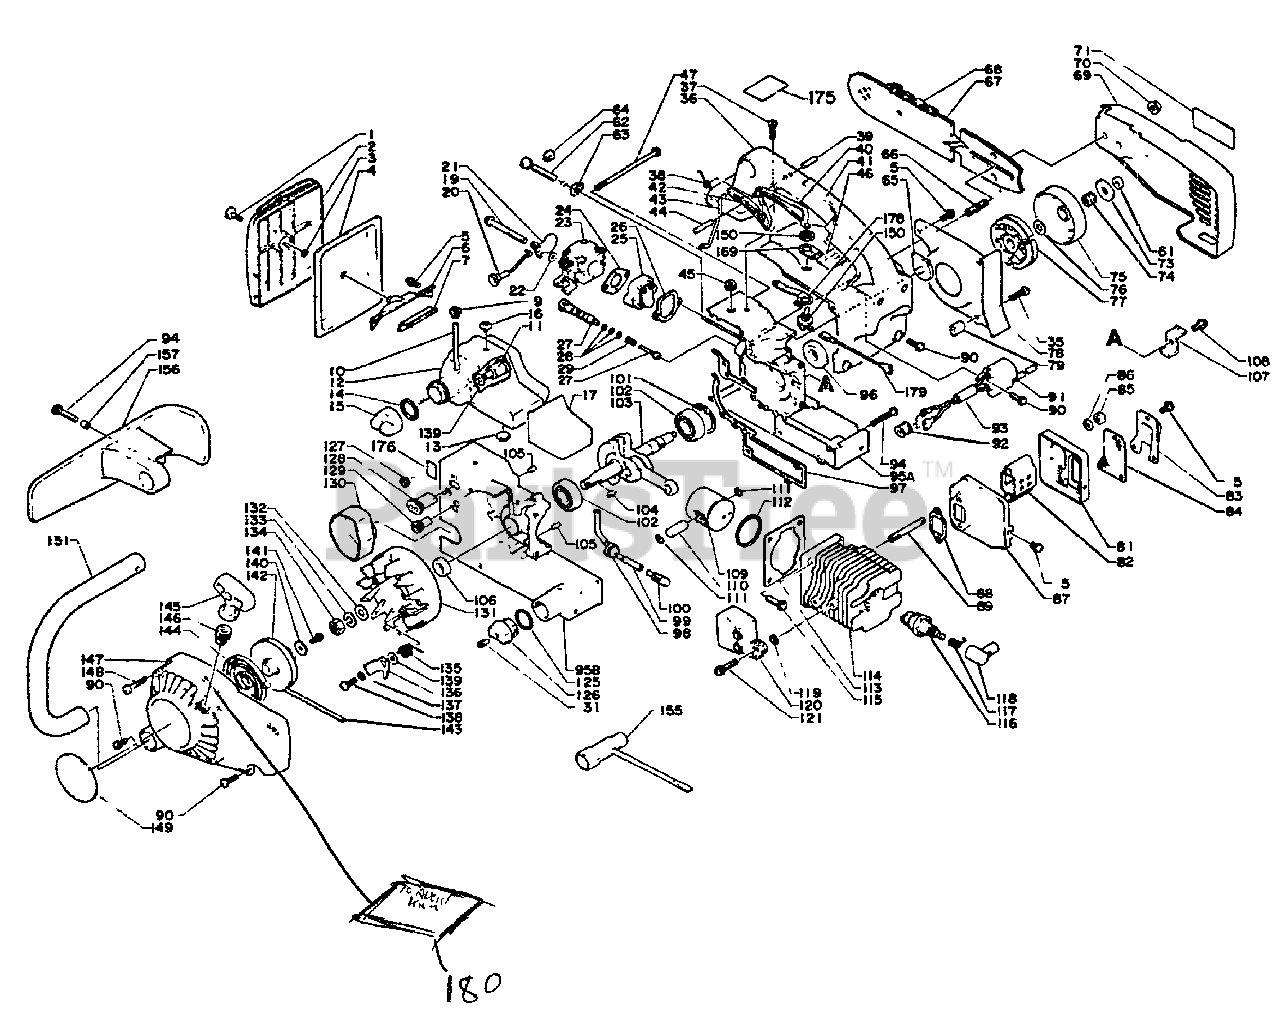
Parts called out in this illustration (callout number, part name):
1	THUMBSCREW
2	COVER, AIR FILTER
3	E-RING 4
4	FILTER, AIR
5	SCREW 4×10
6	BRACKET, AIR FILTER
7	CUSHION
9	GROMMET
10	PIPE, FUEL
11	FILTER, FUEL
12	TANK, FUEL
13	CAP ASSY
14	GASKET
15	CAP
16	VALVE, CHECK
17	CUSHION
19	SCREW 5×50
20	ROD, CHOKE
21	SHUTTER, CHOKE
22	WASHER 5.5×8×0.8
23	CARBURETOR
24	GASKET, INTAKE
25	INSULATOR
26	GASKET, INTAKE
27	AUTO-OILER ASSY
31	VENT ASSY
35	SCREW 4×20
36	HANDLE - TOP
37	SCREW 4×18
38	SPRING
39	PIN, SPRING 5×18
40	LOCKOUT, THROTTLE
41	GRIP, HANDLE
42	LEVER, THROTTLE
43	ROD, THROTTLE
44	PIN, SPRING 5×25
46	LABEL
61	LOCKNUT - 6
62	SCREW, TENSIONER
63	TENSIONER
65	PLUG
66	BOLT, STUD
67	GUIDE BAR
68	SAW CHAIN
69	GUARD, SPROCKET
70	NUT - 6 -- FLANGE
71	LABEL - ECHO
74	BEARING, NEEDLE 8
75	DRUM, CLUTCH
77	CLUTCH ASSY
78	PLATE, SEAL
79	SPACER
82	SILENCER
83	COVER, MUFFLER
84	SCREEN, SPARK ARRESTER
85	SCREW TAPPING 4×8
86	PLATE, EYE
88	GASKET, EXHAUST
89	BOLT, STUD
90	SCREW 4×16
91	COIL, IGNITION
94	SCREW 4×30
95	CRANKCASE KIT
96	SEAL, OIL
97	GASKET, CRANKCASE
98	GROMMET
99	PIPE, OIL
100	FILTER, OIL
101	RING, SNAP Ø32
102	BEARING, BALL 6201
103	CRANKSHAFT
105	PIN, LOCATING 4×8
106	SEAL, OIL
107	CHAIN CATCHER
108	SCREW 5×10
109	PISTON
110	PIN, PISTON
111	RING, SNAP
112	RING, PISTON
113	GASKET, CYLINDER
114	CYLINDER
115	SCREW 5×20
116	SPARK PLUG - CJ-8Y
117	TERMINAL, SPARK PLUG CAP
118	CAP, SPARK PLUG
119	SPACER
120	COIL, IGNITION
121	SCREW 5×22
125	O-RING 16 MM
126	CAP ASSY
127	GROMMET, CHOKE
128	GROMMET
129	GROMMET
130	SEAL
131	FLYWHEEL
132	WASHER 8.5×16×1.2
133	WASHER, SPRING 8
134	NUT 8×1.25
135	SPRING, RETURN
136	RATCHET
137	SPACER 5.2×8×2.1
138	SCREW
139	WASHER 5.5×12×0.8
139	STARTER ASSY
140	WASHER 4 MM
141	SCREW - 4×10
142	REEL, ROPE
143	ROPE, STARTER 3.5×850
144	SPRING, REWIND
146	GUIDE, ROPE
147	COVER, FAN
148	SCREW 4×25
149	LABEL - ECHO
150	SWITCH, IGNITION
151	HANDLE, FRONT
155	T-WRENCH 10×19 MM
156	GUARD
169	LABEL - SWITCH
175	LABEL - NOISE
176	LABEL - CHOKE
178	PLATE - GROUND
179	LEAD - GROUND
180	SCREW - 4×16
181	SCREW - 4×22
192	PLATE, SIDE
